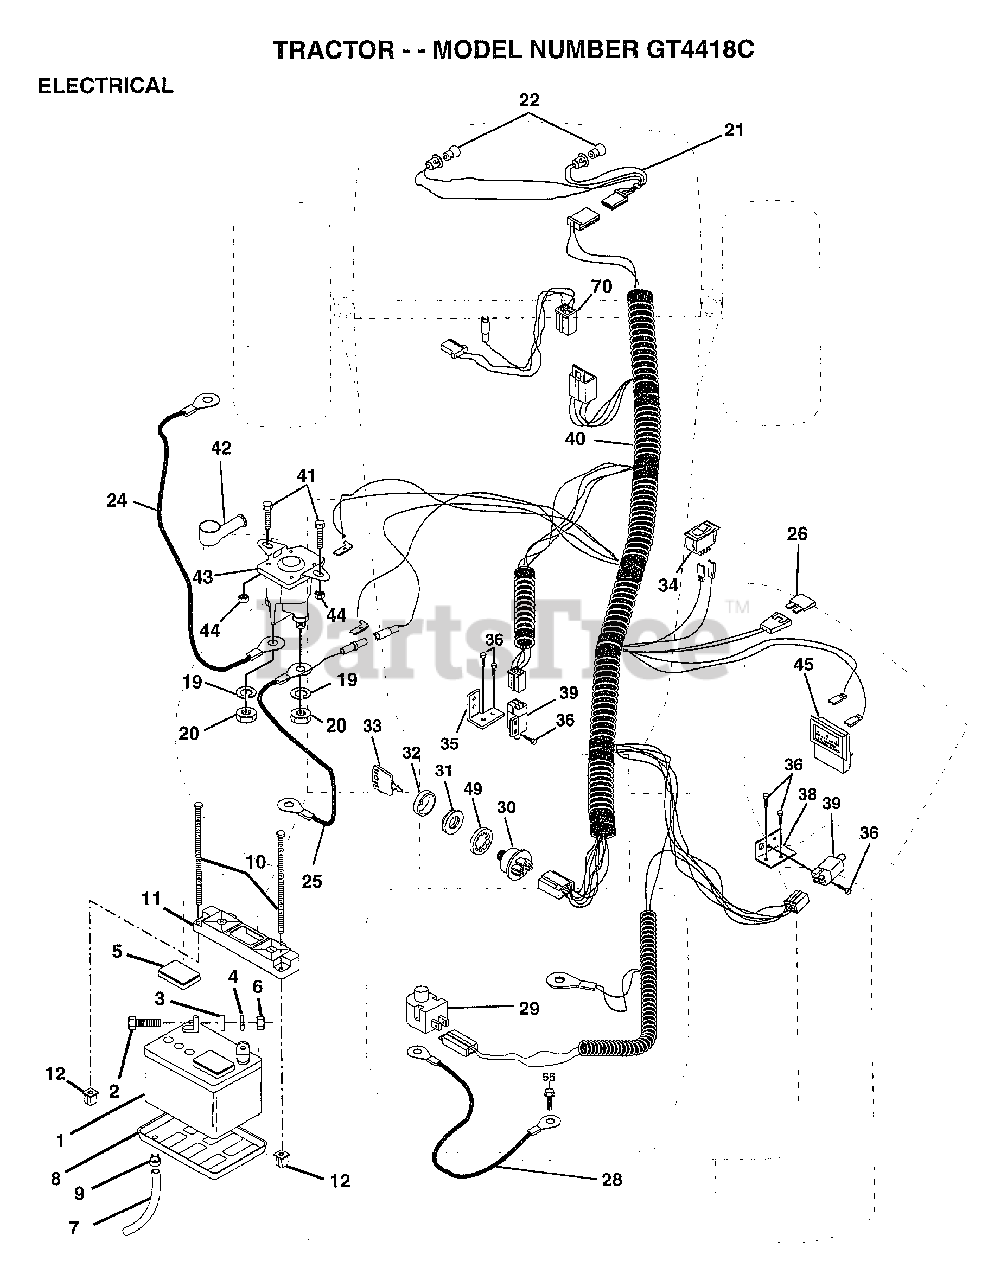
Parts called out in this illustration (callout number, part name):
2	BOLT LT
3	WASHER
4	LOCKWASHER
5	"CAP,BATTERY "
7	"DRAIN TU T, BATT"
8	"TRAY T, BATTERY"
9	HOSE CLAMP T
20	NUT
21	"HARNESS,LIGHT SOC"
22	HEADLAMP BULB
24	"CABLE T, BATTERY"
25	CABLE.6GA.22W/16W
26	FUSE HYT
28	CABLE.GRND.6GA.21
29	SWITCH SEAT
32	COVER KEY SWITCH
33	KEY MLD GEN DELTA
34	SWITCH LT
35	BRACKET LT
36	SCREW
38	BRACKET SWITCH IN
39	SWITCH INTERLOCKT
40	HARNESS.IGN.DASH.
41	BOLT HXHD FIN
44	NUT HXKEP 1/4X20
49	LOCKWASHER
55	SCREW LT
70	HARNESS ENG DUAL
